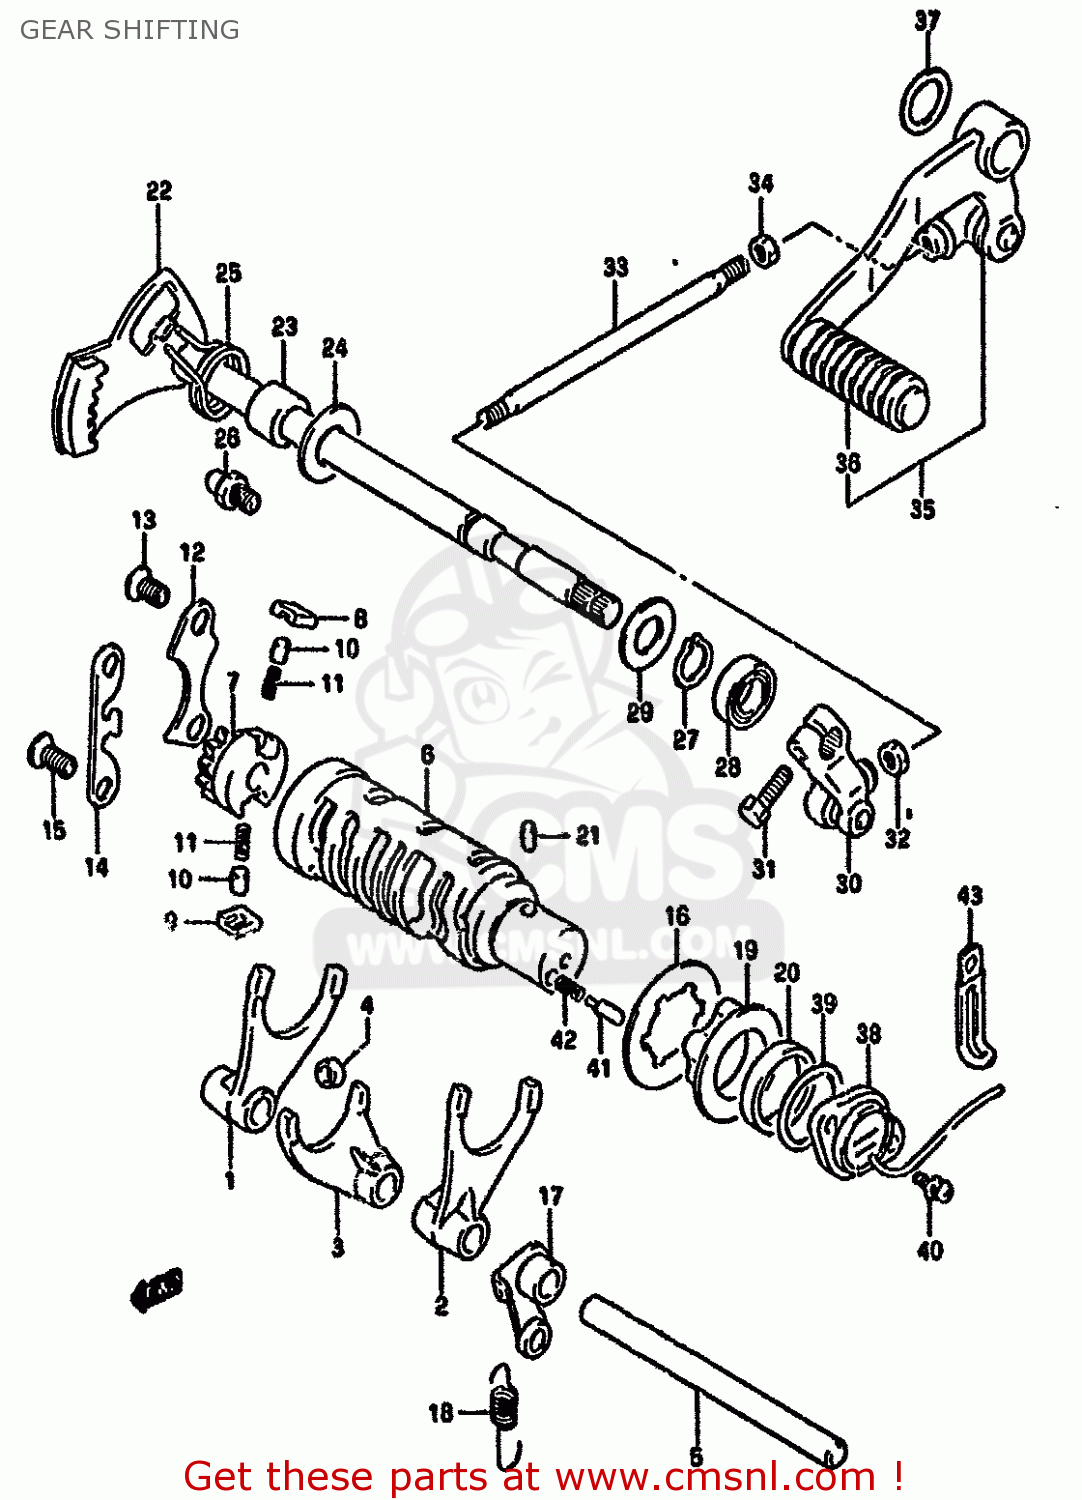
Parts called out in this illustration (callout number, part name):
1	FORK,GEAR SHIFT NO.1
2	FORK,GEAR SHIFT NO.2
3	FORK,GEAR SHIFT NO.3
4	SPACER(6X9.8X6)
5	SHAFT,GEAR SHIFT FORK
6	CAM,GEAR SHIFT
7	GEAR,GEARSHIFT CAM DRIVE
8	PAWL,GEAR SHIFT NO.1
9	PAWL,GEAR SHIFT NO.2
10	PIN(5X8)
11	SPRING
12	LIFTER,GEAR SHIFT PAWL
13	SCREW
14	GUIDE,GEAR SHIFT CAM
15	SCREW
16	WASHER,LOCK
17	STOPPER,GEAR SHIFTING
18	SPRING
19	PLATE,SHIFT CAM STOPPER
20	SPACER (25X30.1X6)
21	PIN 4X6
22	SHAFT,GEAR SHIFT
23	SPACER(12X20X13.8)
24	WASHER
25	SPRING
26	STOPPER,GEAR SHIFT ARM
27	CIRCLIP,12 MM
28	OIL SEAL
29	WASHER (14.2X22X1)
30	ARM,GEAR SHIFT LINK
31	BOLT
32	NUT 6MM
33	ROD,GEAR SHIFT LINK
34	NUT
35	LEVER ASSEMBLY,GEAR SHIFTING
36	RUBBER,GEAR SHIFT PEDAL
37	WASHER(18.2X27X1)
38	BASE ASSY,NEUTRAL SW TERMINAL
39	O-RING (D:2.4 ID:26.2)
40	SCREW
41	PIN(5X15.5)
42	SPRING
43	CLAMP
